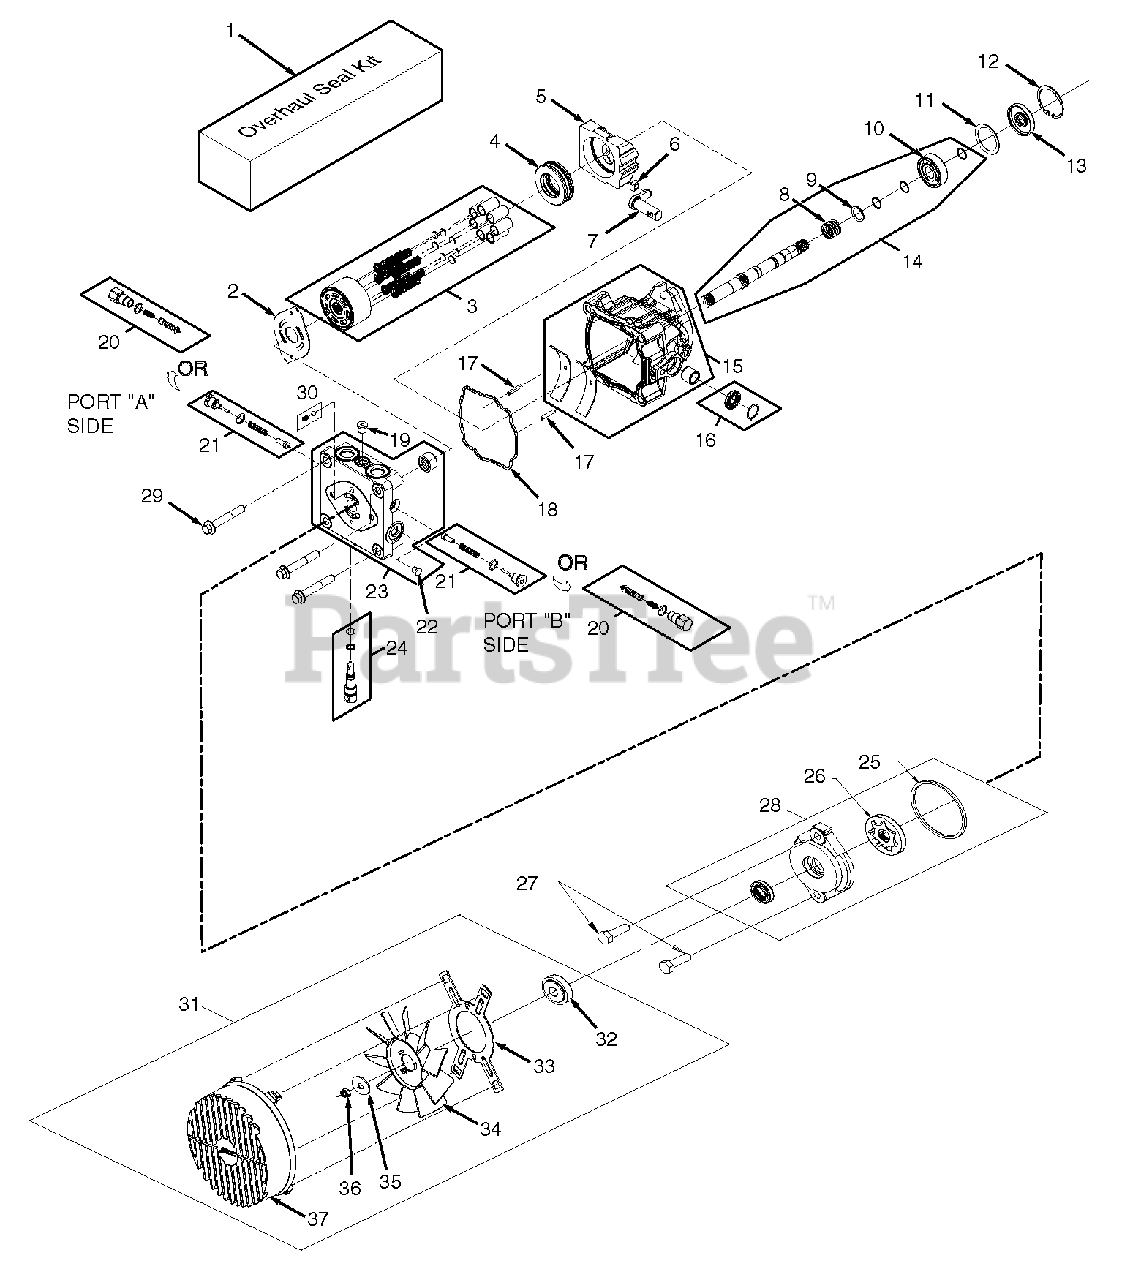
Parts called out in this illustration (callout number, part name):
1	Overhaul Seal Kit
2	Valve Plate
3	Cylinder Block Kit - 16cc
4	Thrust Ball Bearing Assembly
5	Variable Swashplate
6	Slot Guide
7	Trunnion Arm
8	Block Spring
9	Block Thrust Washer
10	Shaft Ball Bearing
12	Retaining Ring
14	Kit, Pump Shaft (keyed thru taper)
15	Housing Kit
16	Trunnion Seal Kit
18	O-Ring
19	Straight Thread Plug
20	Shock Valve Kit (.031 Orifice)
21	Shock Valve Kit (.024 Orifice)
22	Straight Thread Plug
23	End Cap Kit
24	Bypass Valve Kit
26	Gerotor Assembly (.19 cu.in./rev.)
27	Socket Head Cap Screw (M8 x 1.25-25mm)
28	Charge Pump Kit (.19 STD. Splined)
29	Hex Screw, Flanged Head (M10 x 1.50-65mm)
30	Charge Relief Kit
31	Fan Kit
33	Bracket, Shroud
35	Washer
37	Shroud
